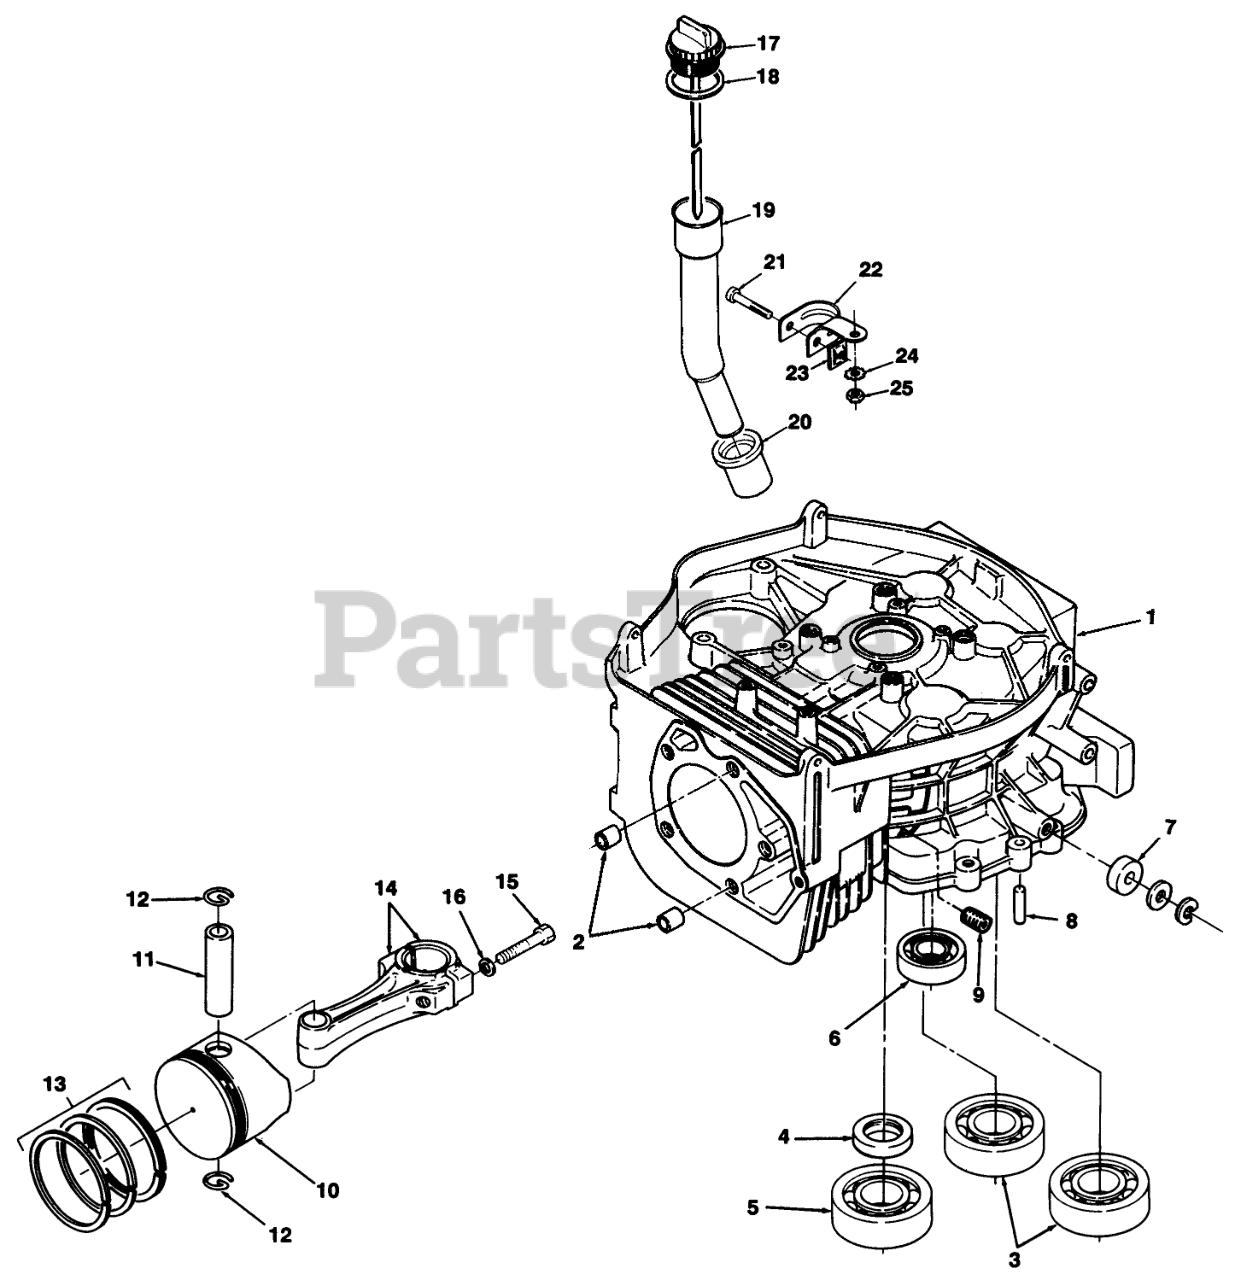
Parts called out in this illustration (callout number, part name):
1	BLOCK-CYLINDER
2	PIN-DOWEL HOLLOW
3	BRNG-BALL BAL SHFT L
4	SEAL-OIL CRNKSHFT UP
5	BEARING-BALL CRANKSH
6	BEARING-BALL CAMSHFT
7	SEAL-GVR SHAFT LEVER
8	PIN-ALIGNMENT
9	Plug-Pipe
10	Kit-Piston (Standard)(Incl. Ref. #11 & 12)
11	PIN-PISTON
12	RING-RETAINING
13	Piston Ring Set-Standard
14	Kit-Connecting Rod (Standard)(Incl. Ref. #15 & 16)
15	Bolt
16	WASHER-CONN ROD
17	Indicator (Incl. Ref. #18)
18	O-Ring
20	Seal
21	SCREW - PAN HEAD
22	BRACKET
23	NUT - SPEED
24	WASHER
25	Nut
